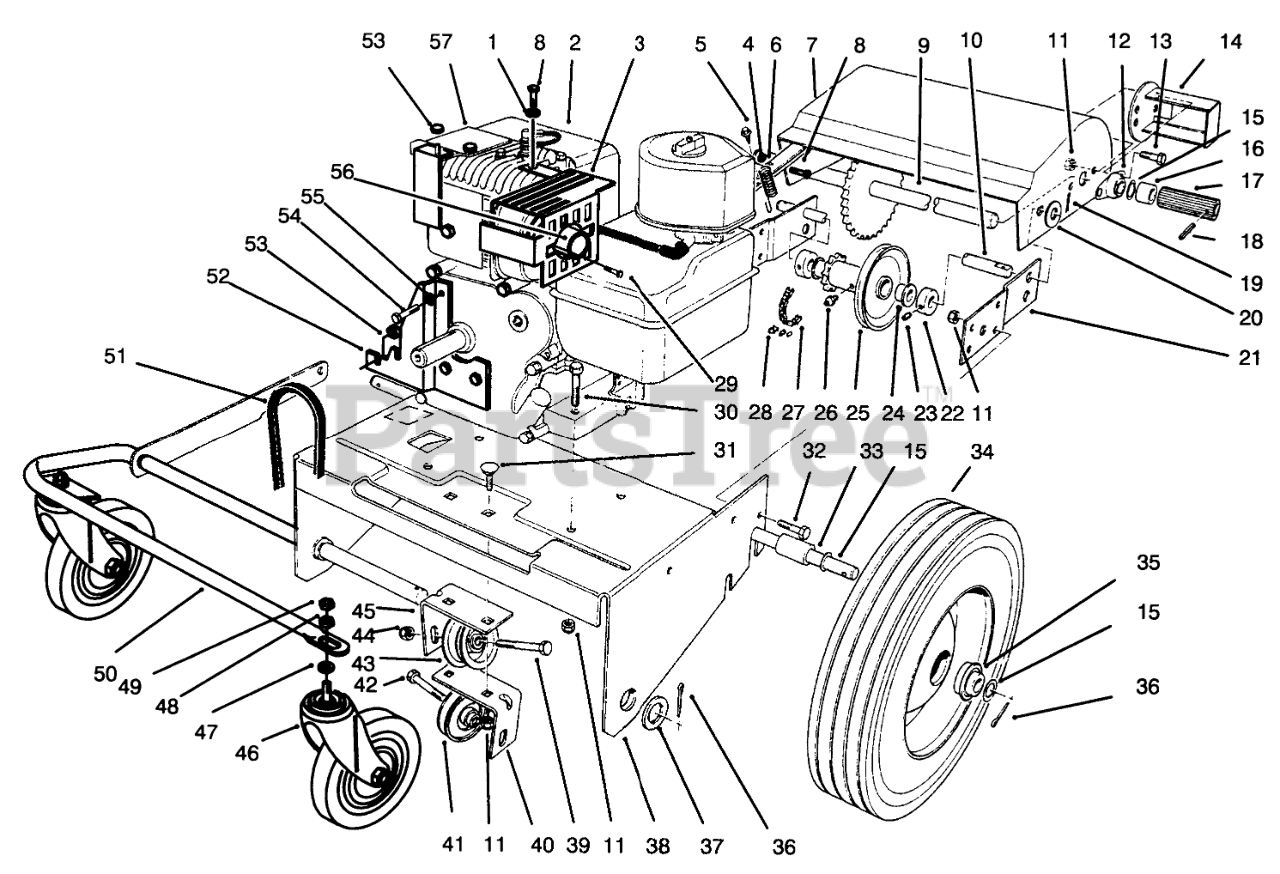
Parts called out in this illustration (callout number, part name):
1	WASHER-BELLEVILLE
3	SHIELD-MUFFLER
4	NUT-LOCK, NI
5	SCREW-HH
6	SPRING-TRACTION
7	Guard
8	SCREW-HH
9	SHAFT-WHEEL, FRICTION
10	SHAFT-IDLER
11	NUT-LOCK, NI
12	BEARING-MOUNT, FLANGE
13	SCREW-HH
14	Guard
15	WASHER
16	SPACER
17	WHEEL-FRICTION
18	PIN-ROLL, SLOTTED
19	PIN-COTTER
20	WASHER-FLAT
21	Bracket Mounting
22	Collar (Incl. Ref #23)
23	SCREW-SET, HSH
24	BUSHING-FLANGE
25	Idler Assembly (Incl. Ref #24 & 26)
26	FITTING-GREASE
27	Chain (Incl. Ref #28)
28	LINK-CONNECTING, NO. 35
29	SCREW - 94126 F/W
30	SCREW-HH
31	SCREW-CARR
32	SCREW-HH
33	SPACER-AXLE
34	Wheel (Incl. Ref #35)
35	BEARING
36	PIN-COTTER
37	WASHER-FLAT
38	Engine Plate
39	SCREW-HH
40	Bracket-Idler Mount L.H.
41	PULLEY-IDLER
42	SCREW-HH
43	PULLEY-IDLER
44	NUT-LOCK, NI
45	Bracket-Idler Mount R.H.
46	CASTER
47	WASHER-LOCK/INT
48	NUT-HH
49	NUT-LOCK, NI
50	Support-Front Wheel
51	BELT-V
52	Guard
53	NUT-LOCK, NI
54	SCREW-HH
55	WASHER-LOCK/INT
56	WA - EXHAUST EXTENSION
57	MTG BRKT WA B
